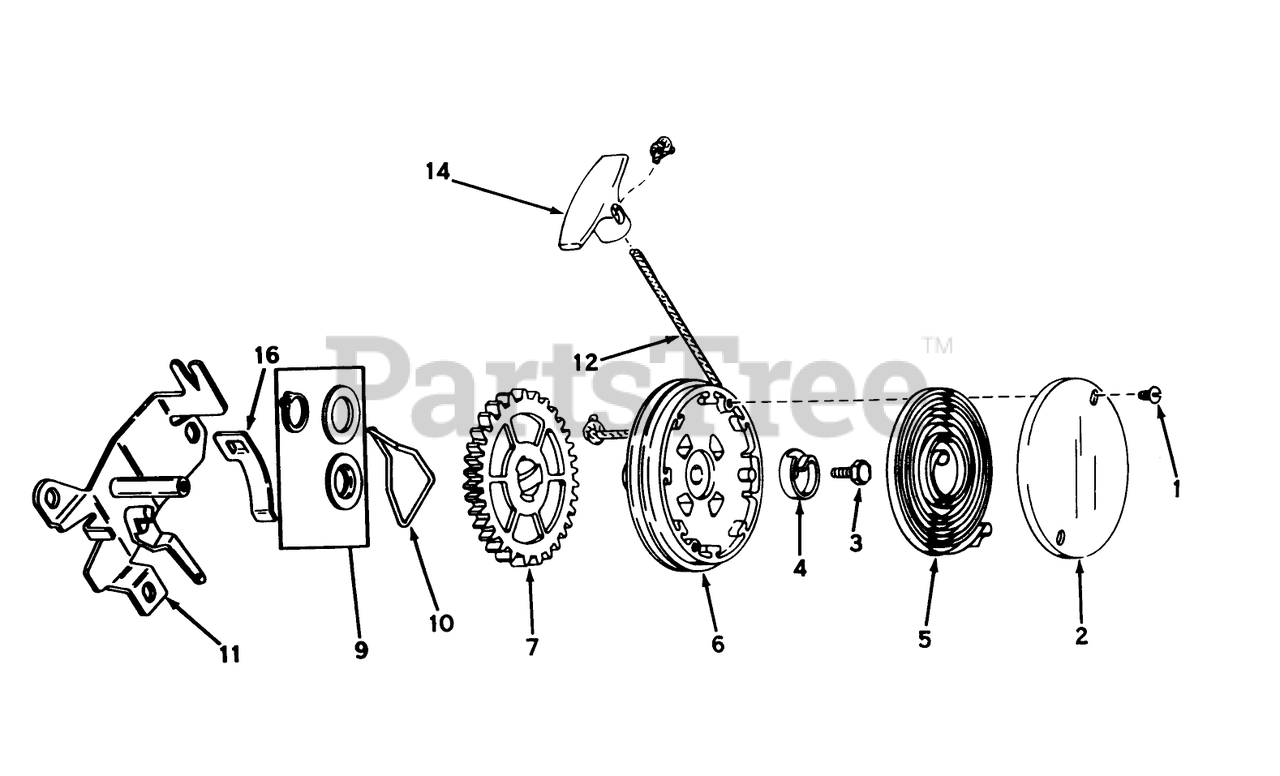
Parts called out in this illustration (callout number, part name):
2	Cover, Spring
3	Screw, Hex Washer Head
4	Hub Spring
5	Spring, Rewind
6	Pulley Assy. (Incl. No. 9)
9	Kit, Thrust Wash. & Snap Rg.
11	Bracket Assy., Mounting
12	Rope-Starter
14	Handle-Starter
16	Clip Rope
